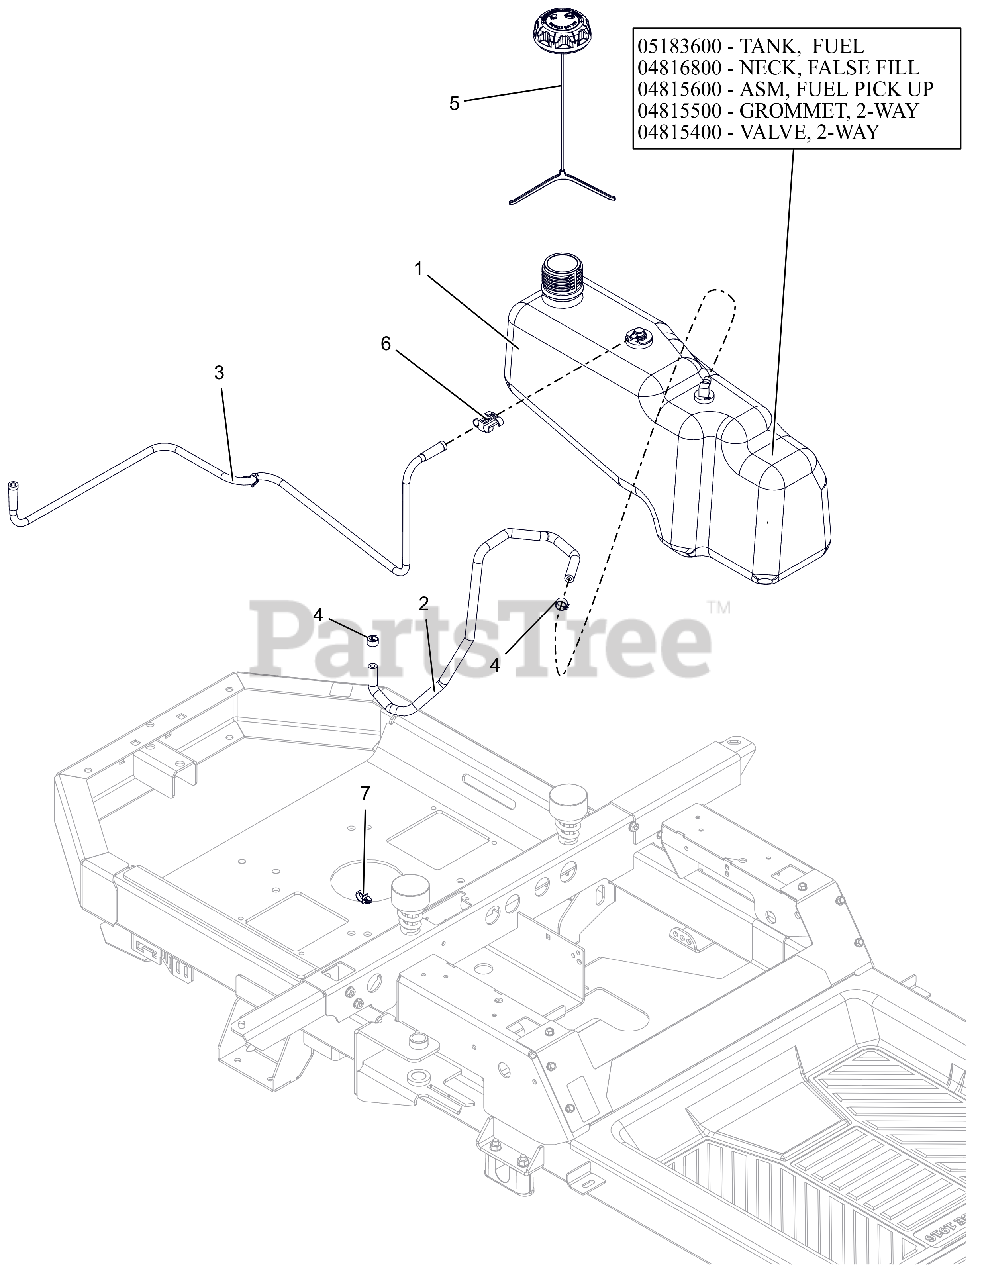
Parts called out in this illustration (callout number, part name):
1	ASM, FUEL TANK - ZTX
1	TANK, FUEL-ZTX
1	NECK, FALSE FILL ZOOM/ZT
1	ASM, FUEL PICK-UP ZOOM/ZT 2015
1	GROMMET, 2-WAY
1	VALVE, 2-WAY
2	HOSE, .25 LOW-PERM BULK GAS
3	LINE, FUEL VENT KOHLER SMCHOKE
4	CLAMP, FUEL LINE
5	CAP, FUEL VENT-IN 2.25" RATCH.
6	CLIP, T, .38-.50
7	ROUTING CLIP (1/2" ID)
